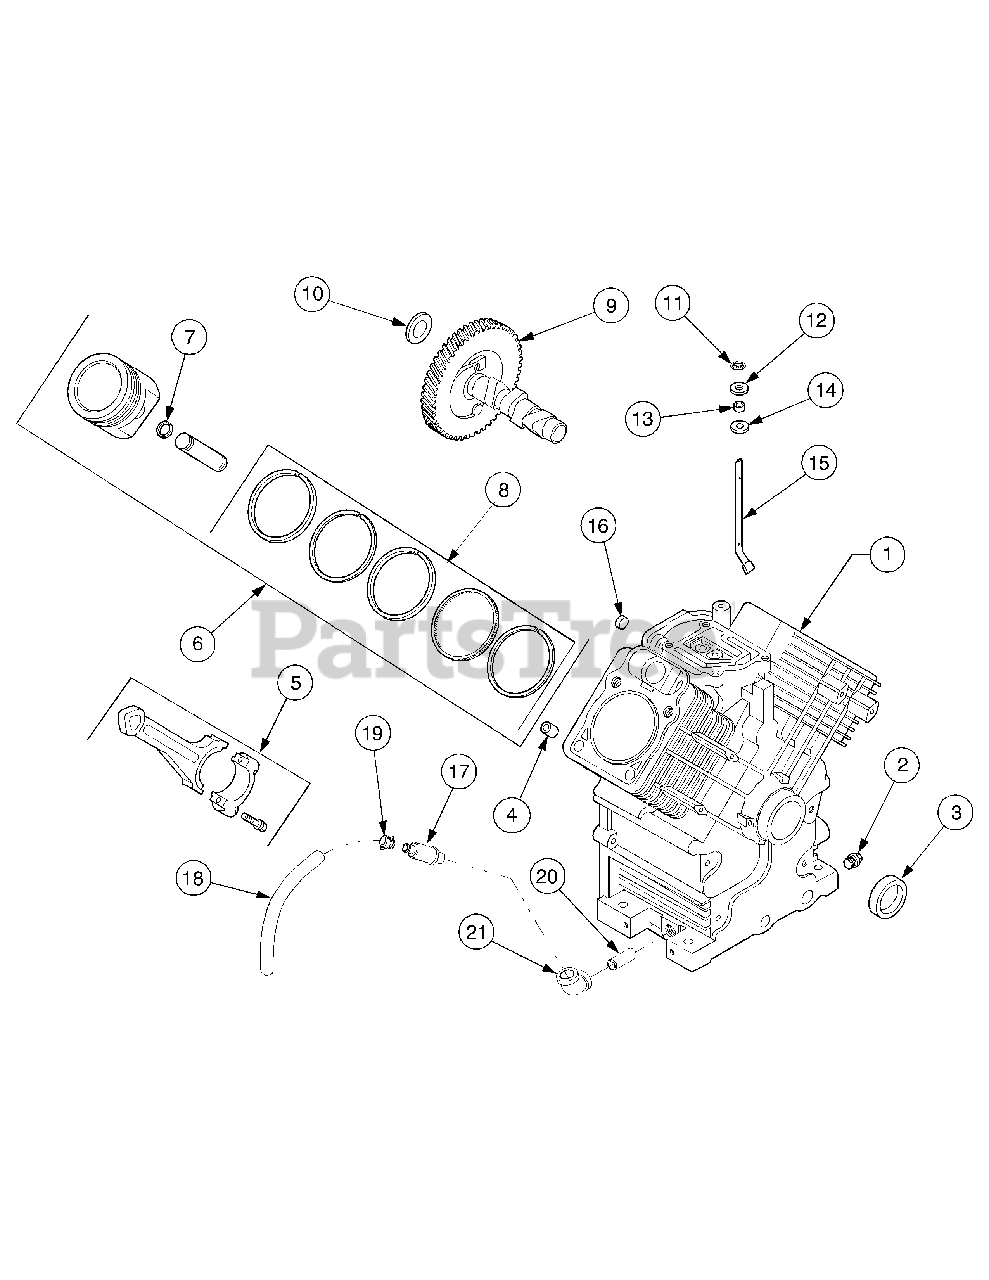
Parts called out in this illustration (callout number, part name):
1	Cylinder Block, (Use Miniblock)
2	Plug, Hex Hd, 3/8
3	Seal, Front Oil
4	Pin, Locating Dowel
5	Rod, Connecting, Std
5	Rod, Connection, .010 / .25mm
6	Piston w/Ring Set, Std
6	Piston w/Ring Set, .08mm
6	Piston w/Ring Set, .010 / .25mm
6	Piston w/Ring Set, .020 / .50mm
7	Retainer, Piston Pin
8	Ring Set, Std
8	Ring Set, .010 / .25mm
8	Ring Set, .020 / .50mm
9	Camshaft Assembly
10	Shim, Camshaft, .0320 (Red)
10	Shim, Camshaft, .0400 (Black)
10	Shim, Camshaft, .0280 (White)
10	Shim, Camshaft, .0300 (Blue)
10	Shim, Camshaft, .0340 (Yellow)
10	Shim, Camshaft, .0360 (Green)
10	Shim, Camshaft, .0380 (Gray)
11	Ring, Retainer
12	Washer, Nylon
13	Seal, Governor Cross Shaft
14	Washer, Plain
15	Shaft, Governor Cross
16	Plug, Cup
17	Drain, Oil
18	Hose, Oil Drain
20	Pipe, Straight, 3/8 NPT x 2.0
21	Elbow, 90 Degree
